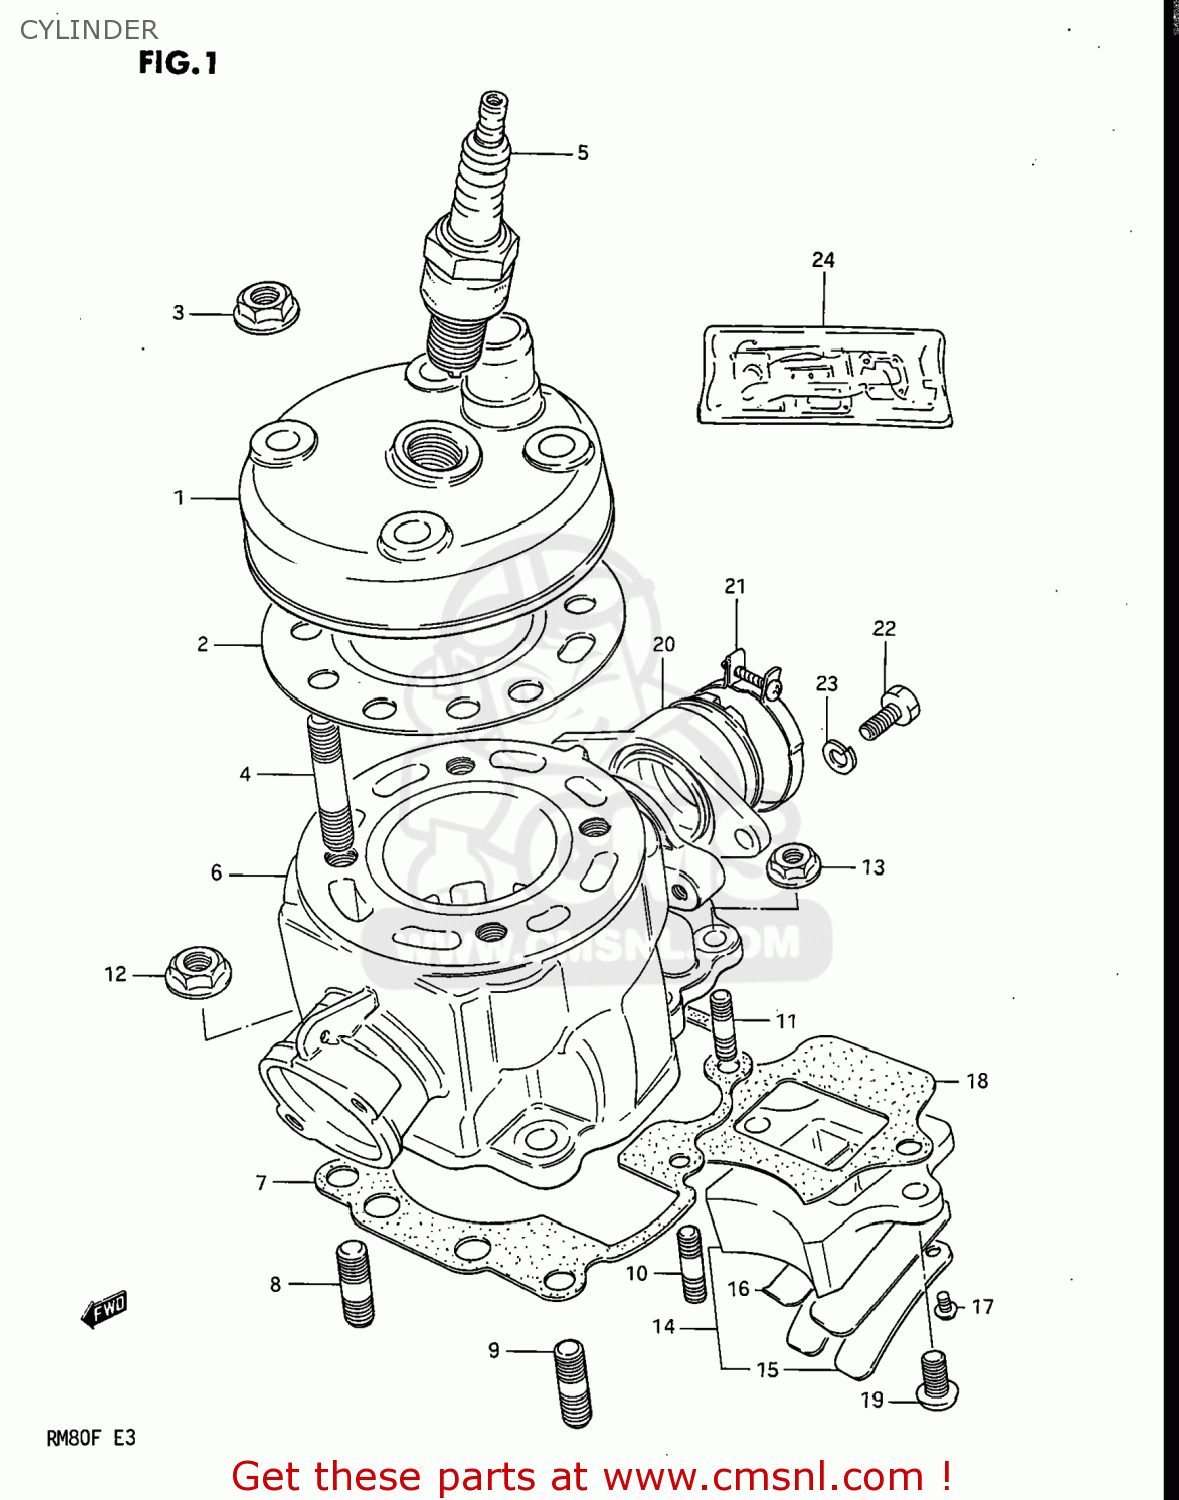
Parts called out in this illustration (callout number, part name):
1	HEAD,CYLINDER
2	GASKET,CYLINDER HEAD
3	NUT 8MM
4	BOLT,STUD
5	SPARK PLUG
6	CYLINDER
7	GASKET,CYLINDER (MCA)
8	BOLT,STUD(8X20)
9	STUD BOLT
10	STUD BOLT L:20
11	STUD 6X16
12	NUT 8MM
13	NUT 6MM
14	VALVE ASSY,REED
15	STOPPER,REED VALVE
16	VALVE,REED
17	SCREW,REED VALVE
18	GASKET,REED VALVE (MCA)
19	SCREW
20	PIPE,INTAKE
21	CLAMP
22	BOLT
23	LOCK WASHER
24	GASKET SET (MCA)
